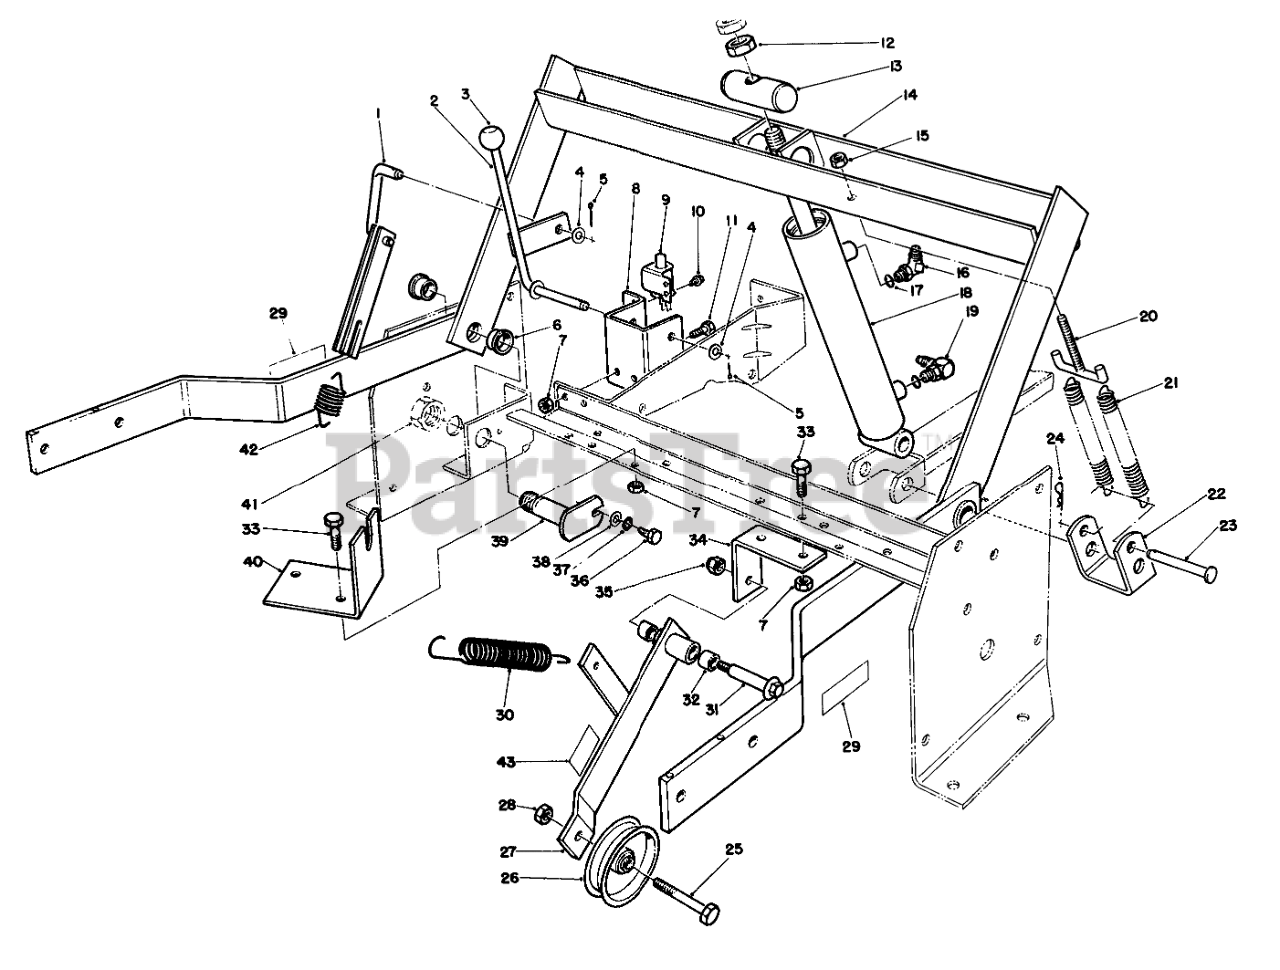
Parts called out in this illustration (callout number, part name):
1	Link-Parking Brake
2	Brake Lever
4	WASHER-FLAT
5	PIN-COTTER
6	BEARING-FLANGE
7	NUT-LOCK, NI
8	Bracket-Parking Brake
9	SWITCH-BRAKE, PARKING
10	SCREW-TAPTITE
11	SCREW-HH
12	NUT-JAM
13	CYL.PIVOT PIN
14	Frame-Lift (Incl. Ref. #6)
15	NUT-HEX, SIDE DEFORM
16	FITTING-45 DEG
17	O-RING
18	CYLINDER - LIFT
19	FITTING-ELBOW, 90
20	T-HOOK W A
21	SPRING_EXTENSION
22	SPRING BRACKET
23	PIN-CLEVIS
24	PIN-HAIR
25	SCREW-HH
26	PULLEY-IDLER
27	Lever-Idler (Incl. Ref. #43)
28	NUT-LOCK, NI
29	WARNING DECAL
30	IDLER EXT SPRING
31	BOLT-WHEEL
32	BUSHING
33	SCREW-HH
34	JACKSHFT IDLR BRKT
35	NUT-LOCK
36	SCREW-HH
37	WASHER-LOCK
38	WASHER-FLAT
39	Pin-Pivat
40	TRACT CABLE BRKT
41	NUT-LOCK, NI
42	PARK BRAKE SPRING
43	DECAL-WARNING
